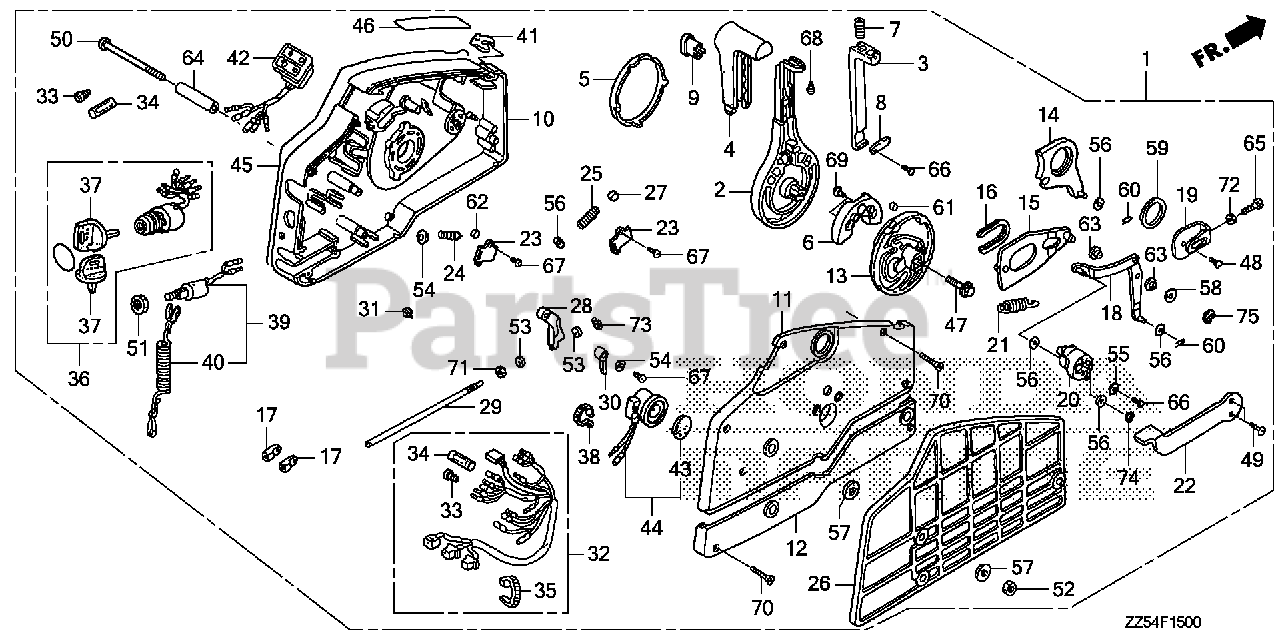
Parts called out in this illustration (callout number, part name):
1	BOX ASSY., REMOTE CONTROL (NHK MEC)
1	BOX ASSY., REMOTE CONTROL (HI-LEX)(A/T)
2	HANDLE, REMOTE CONTROL
3	LEVER, HANDLE LOCK
4	GRIP, REMOTE CONTROL HANDLE
5	CAP, HANDLE
6	BLOCK, NEUTRAL LOCK
7	SPRING, REMOTE CONTROL HANDLE
8	PLATE, LEVER SETTING
9	COVER, GRIP
10	HOUSING, REMOTE CONTROL BOX (A)
11	HOUSING, REMOTE CONTROL BOX (B)
12	HOUSING, REMOTE CONTROL BOX (C )
13	WHEEL, CONTROL
14	ARM, SHIFT LINK
15	PLATE, SLIDING
16	COLLAR, SLIDING PLATE
17	PIVOT, SHIFT
18	ARM, LINK JOINT
19	BRACKET, LINK JOINT
20	WHEEL, ACCELERATOR
21	SPRING, ACCELERATOR WHEEL
22	LEVER, IDLE
23	PLATE, SPRING SETTING
24	SPRING, SHIFT CLICK
25	SPRING, CHOKE RETURN
26	SPACER, REMOTE CONTROL BOX
27	SPACER, CLICK SPRING
28	BLOCK, THROTTLE FRICTION
29	BOLT, FRICTION
30	SPACER, NEUTRAL SWITCH
31	SPACER, CABLE CLAMP
32	CABLE ASSY., REMOTE CONTROL (B) (FOR 4-LED)
33	PLUG, CONNECTOR (INNER) (TROLLING CONTROL)
34	PLUG, CONNECTOR (OUTER) (ENGINE NO.)
35	TIE, CABLE (NATURAL 2.4X92) Use up to Frame SN 1300359.
36	SWITCH ASSY., COMBINATION DUAL QTY = (2) (SINGLE)
36	SWITCH ASSY., COMBINATION (SINGLE) (DUAL)
37	KEY ASSY., COMBINATION SWITCH (35100-ZV5-003 ONLY) DUAL QTY = (4) (SINGLE)
38	BAND (BLACK 3.5X140)
39	SWITCH ASSY., EMERGENCY STOP
40	WIRE, EMERGENCY (SINGLE) (DUAL)
41	CLIP, EMERGENCY LOCK
42	LAMP ASSY., INDICATION
43	PLATE, TURN SIGNAL BUZZER DUAL QTY = (2) (SINGLE)
44	BUZZER, WARNING DUAL QTY = (2) (SINGLE)
45	PLATE, REMOTE CONTROL (CAUTION PICT=SILVER) (FOR 4-LED)
45	PLATE, REMOTE CONTROL (COUTION COLOR=RED & YELLOW)
46	MARK, FAST IDLE
47	BOLT, FLANGE (8X35) Use from Frame SN 4800713.
48	SCREW, PAN (6X10)
49	SCREW, FLAT (5X12) Use from Frame SN 4800713.
50	SCREW (6X95)
51	NUT, HEX. (16MM) DUAL QTY = (2) (SINGLE)
52	NUT, HEX. (6MM)
53	WASHER, PLAIN (4MM) Use from Frame SN 4800713.
54	WASHER, PLAIN (5MM)
55	WASHER, PLAIN (5MM)
56	WASHER, PLAIN (6MM) Use from Frame SN 4800713.
57	WASHER (6MM)
58	WASHER, PLAIN (8MM) Use from Frame SN 4800713.
59	WASHER (28MM)
60	PIN, LOCK (6MM)
61	PIN (6X6)
62	ROLLER, CLICK
63	COLLAR, LINK JOINT
64	COLLAR, DISTANCE (6X10X43.5)
65	BOLT, HEX. (5X16)
66	SCREW, PAN (5X10)
67	SCREW, TAPPING (5X10)
68	SCREW, TAPPING (5X12)
69	SCREW, TAPPING (6X16)
70	SCREW, TAPPING (5X25)
71	NUT, HEX. (6MM)
72	NUT, HEX. (5MM)
73	E-RING (3MM)
74	E-RING (4MM)
75	E-RING (7MM)
